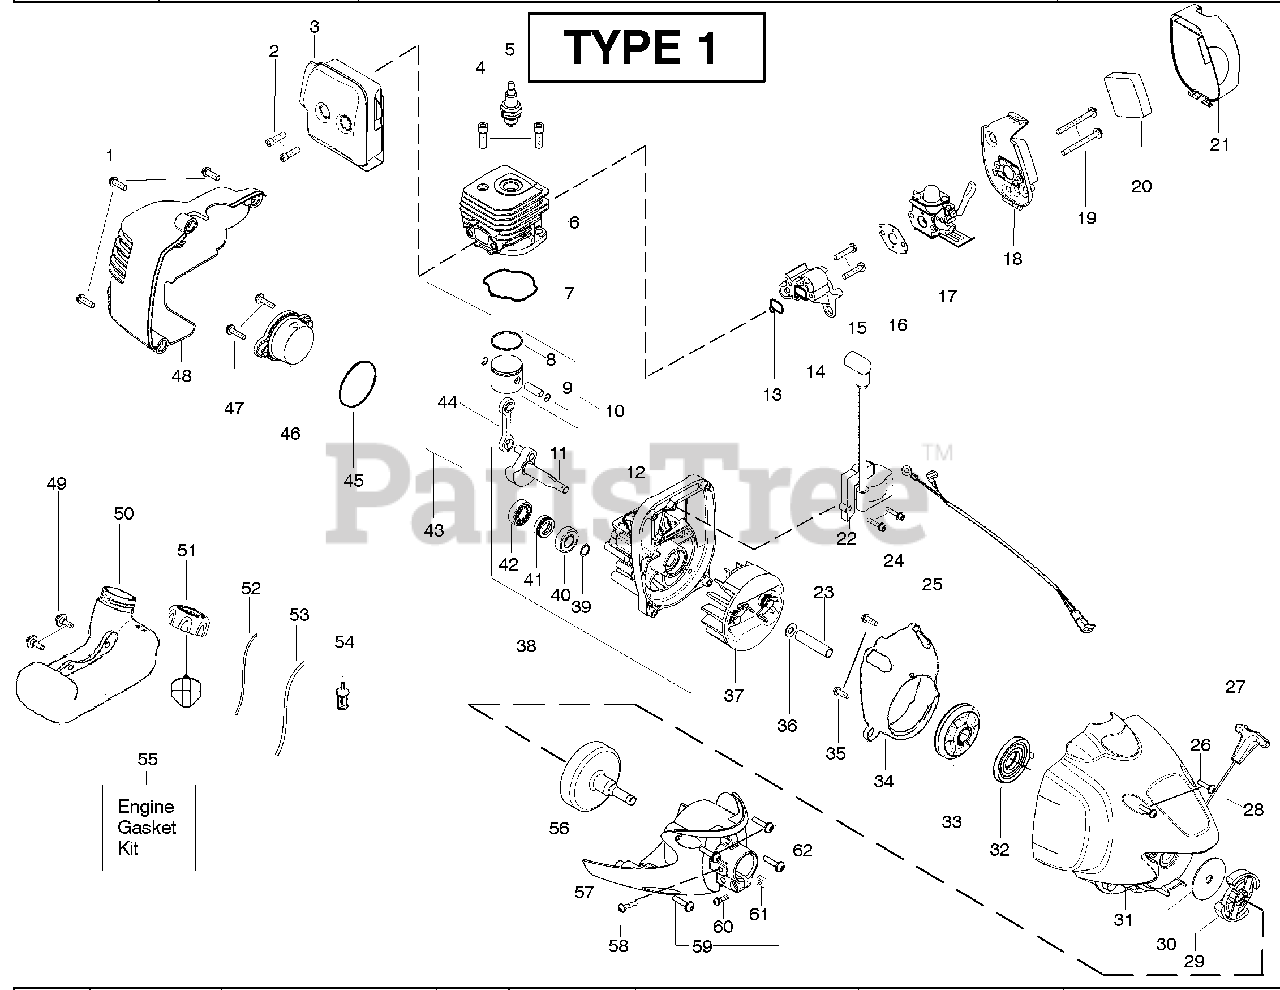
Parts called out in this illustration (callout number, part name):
3	Assy-Muffler/Shield
4	Screw-Cylinder
5	Spark Plug (RCJ 6Y)
7	Seal-Cylinder (kit)
8	Piston Ring
9	Retainer-Piston Pin
10	Kit - Piston
11	Assy-Crankshaft
12	Assy-Crankcase
13	Seal-Cyl/Carb(kit)
16	Gasket-Carb (kit)
17	Kit-Carb(C1U-W19)
20	Foam-Air Filter
21	Cover-Air Box
22	Ignition Module
23	Spacer-Flywheel
25	Assy-Switch wire
27	Handle-Starter
30	Washer-Clutch
31	Assy-Fan Hsg
32	Spring-Starter
33	Kit-Starter Pulley
36	Washer-Clutch Flat
37	Assy-Flywheel
38	Assy-C'case & C'shaft
39	Retain. Ring-C'shaft
40	Outer Bearing
42	Inner Bearing
43	Kit-piston/rod
44	Kit-Conn. Rod
45	O-Ring-C'case (kit)
46	Assy-Plug
49	Retainer-Tank
50	Assy-Fuel Tank
51	Assy-Fuel Cap
52	Kit-Fuel Line (Small)
53	Kit-Fuel Line (Large)
54	Assy-Fuel Pickup
55	Kit-Engine Gasket
56	Assy-Clutch Drum
57	Assy-Clutch Cover
